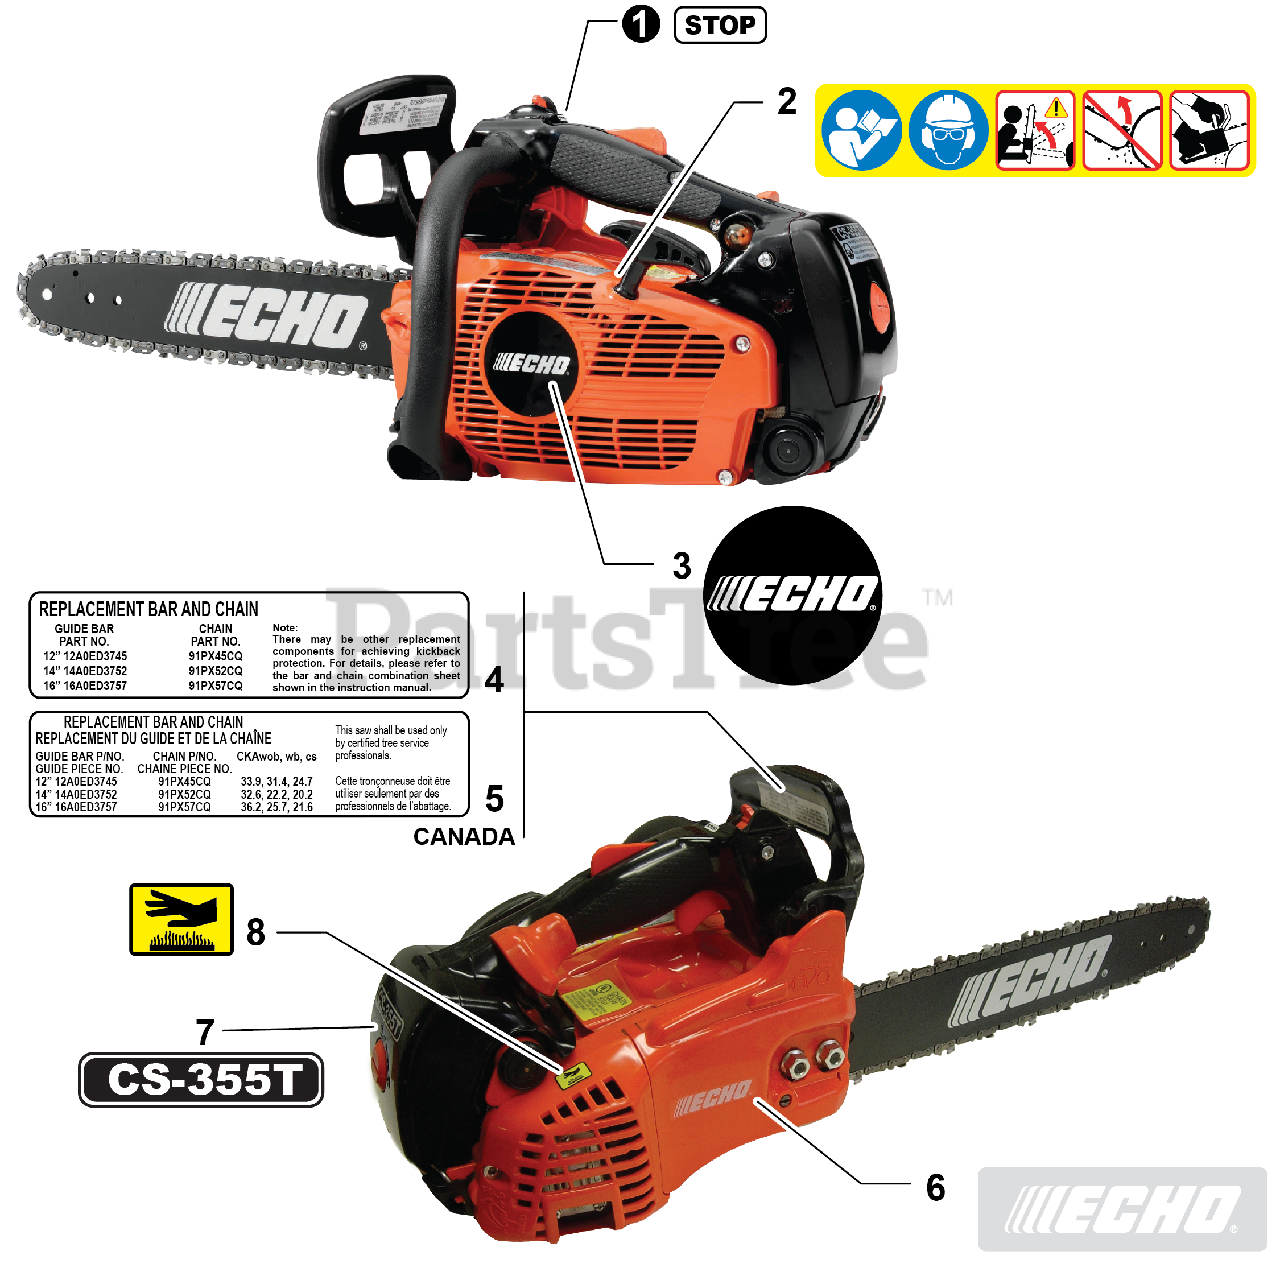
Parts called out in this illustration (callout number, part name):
1	LABEL, STOP
2	LABEL, CAUTION
3	LABEL, ECHO
4	LABEL, BAR & CHAIN
5	LABEL, BAR & CHAIN
6	LABEL, ECHO
7	LABEL - MODEL CS-355T
8	LABEL, CAUTION - HOT
